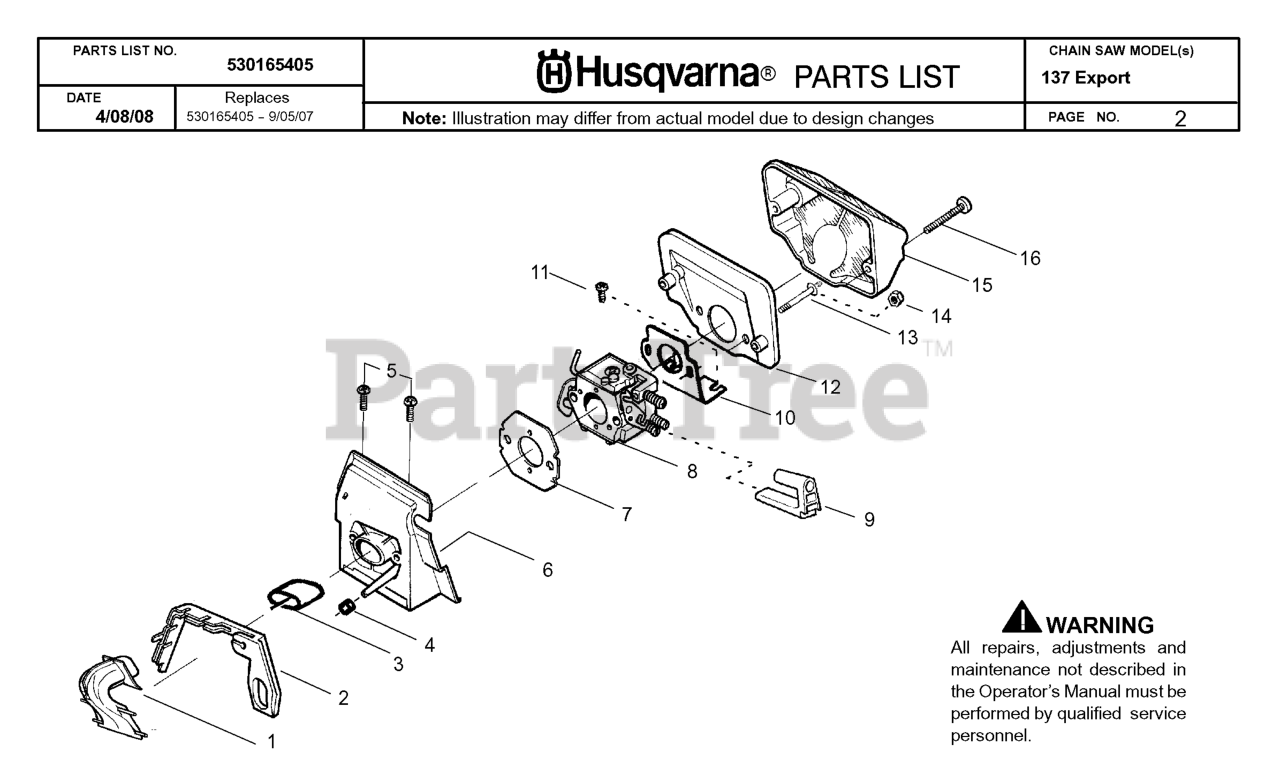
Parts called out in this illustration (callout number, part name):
1	INTAKE HORN
2	TURBO CLEAN SEAL
3	INTAKE PIPE
4	IMPULSE PIPE
6	CARB ADAPTOR
7	GSKT,CARB 36/41
12	AIR FILTER (BOTTOM)
13	STUD-CARBURETOR
15	AIR FILTER - TOP
